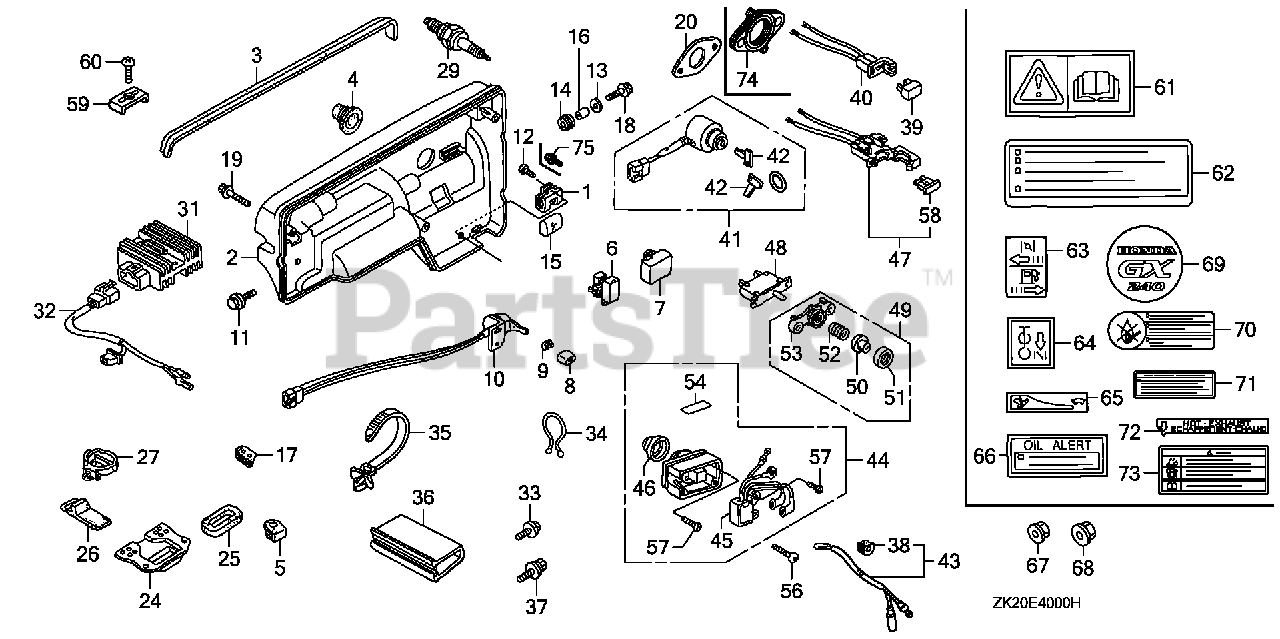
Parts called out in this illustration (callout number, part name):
1	CLIP, WIRE
2	CASE, CONTROL *R280* (POWER RED)
3	RUBBER, CONTROL
4	GROMMET, MAIN WIRE
5	GROMMET, SWITCH WIRE
8	KNOB, PETCOCK LEVER
9	BUSH, CONTROL KNOB
10	SWITCH ASSY., ENGINE STOP
11	BOLT, FLANGE (8X20)
12	SCREW, GLOVE BOX
13	WASHER, AIR DUCT
14	RUBBER, CONTROL BOX
15	TUBE, CORD
16	COLLAR, CONTROL BOX
17	GROMMET, TUBE
18	BOLT, FLANGE (6X18)
19	BOLT, FLANGE (6X40)
29	SPARK PLUG (W20EPR-U) (DENSO)
75	BOLT, FLANGE (6X12) (CT200)
